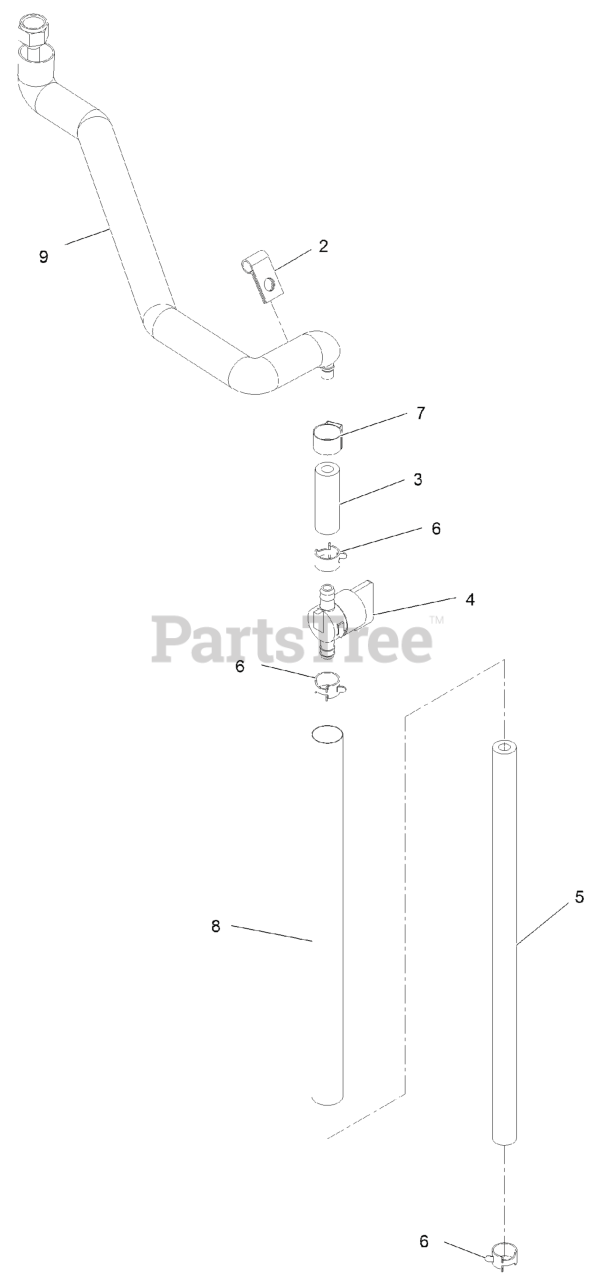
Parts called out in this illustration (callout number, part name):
2	CLIP-CLOSED, INSULATED
3	Hose-Fuel
4	VALVE-FUEL
5	HOSE-FUEL
6	CLAMP-HOSE
7	Clamp-Hose, Fuel
8	Sleeve, Thermal
9	SLEEVE-THERMAL,
